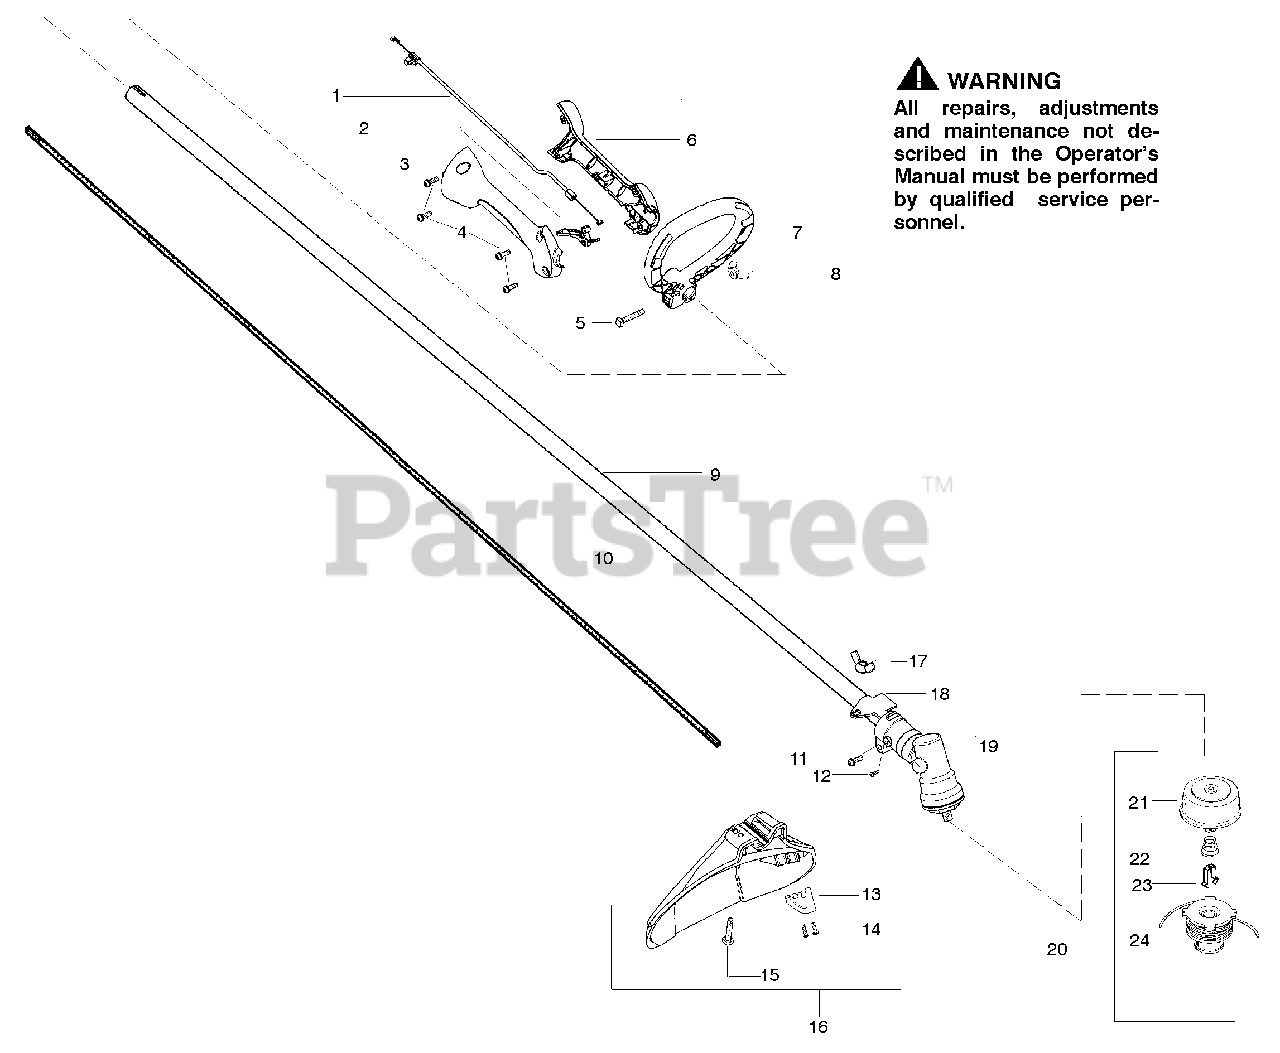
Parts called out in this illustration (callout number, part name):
1	Assy-Throttle Cable
3	Throttle Hsg. (Right)
4	Screw-Throttle Hsg.
5	Bolt-Handle/Shield
6	Throttle Hsg. (Left)
7	Assy-Handle Assist
8	Wingnut
9	Assy-Drive Shaft Hsg.
10	Shaft- Flex
12	Screw- Alignment
13	Line Limiter
14	Screw-Line Limiter
16	Kit-Shield Assy
17	Wingnut
18	Bracket-Shield
19	Assy-Gearbox
20	Accy-TNG VI Cutting Head
21	Assy-Hub
22	Spring-Compression
23	Clip-Retainer-Head
24	Accy- Spool w/Line
